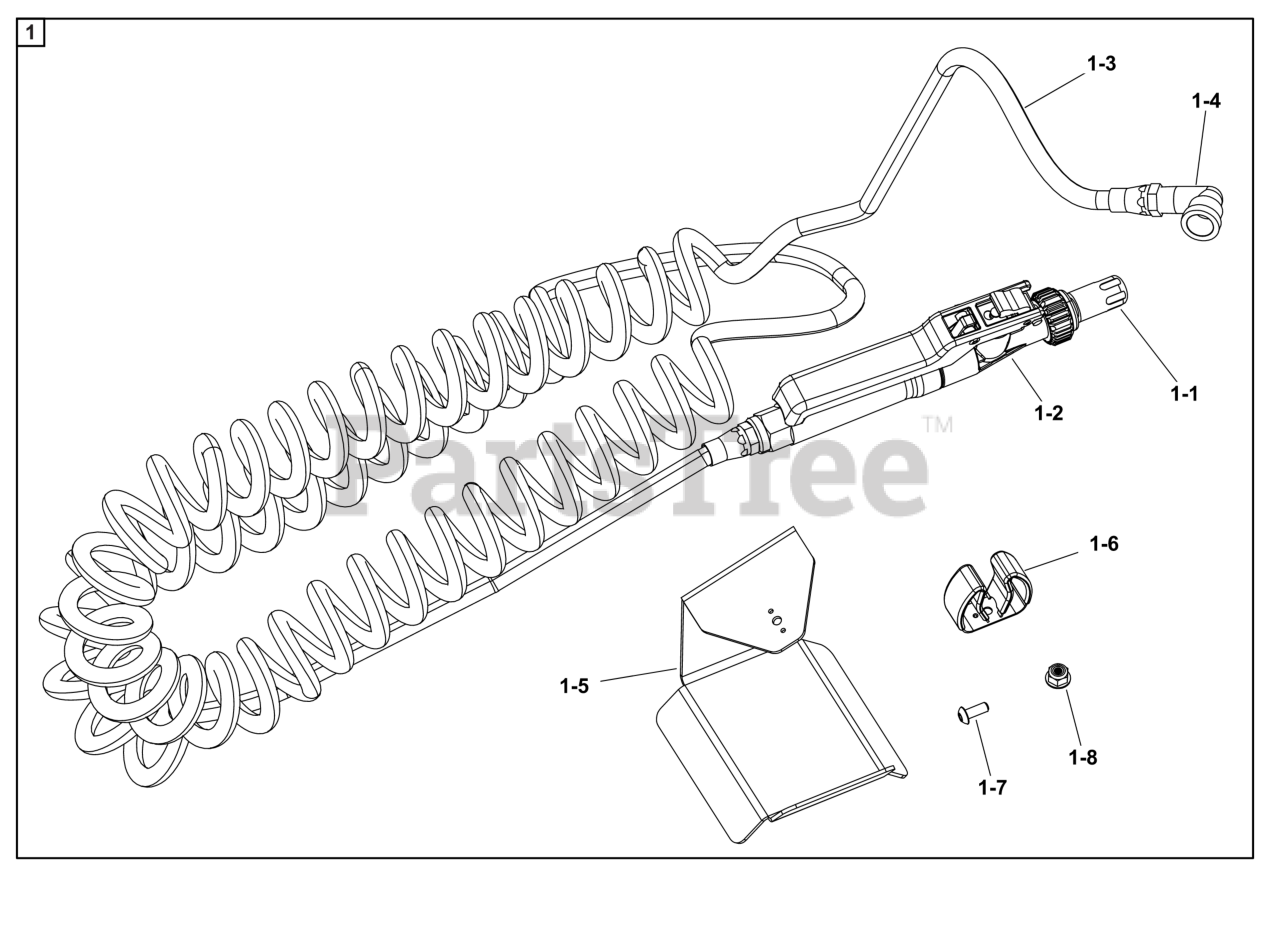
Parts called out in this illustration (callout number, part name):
1	ASSY, SPRAY WAND (SPW-200-1)
1-1	NOZZLE, SPRAY WAND (G0169)
1-2	SPRAY GUN, 1/4 FPT
1-3	HOSE, COIL 25 FT
1-4	STREET ELBOW, 1/4 MPT-1/4 FPT, 90 DEG
1-5	BRACKET, COIL HOSE HOLDER
1-6	CLIP, .750" O.D. OIL DRAIN HOSE
1-7	SCR-CAP, BSH #10-24 X .500" SS188
1-8	NUT-HEX-NYLK, FLG .#10-24 SS188
